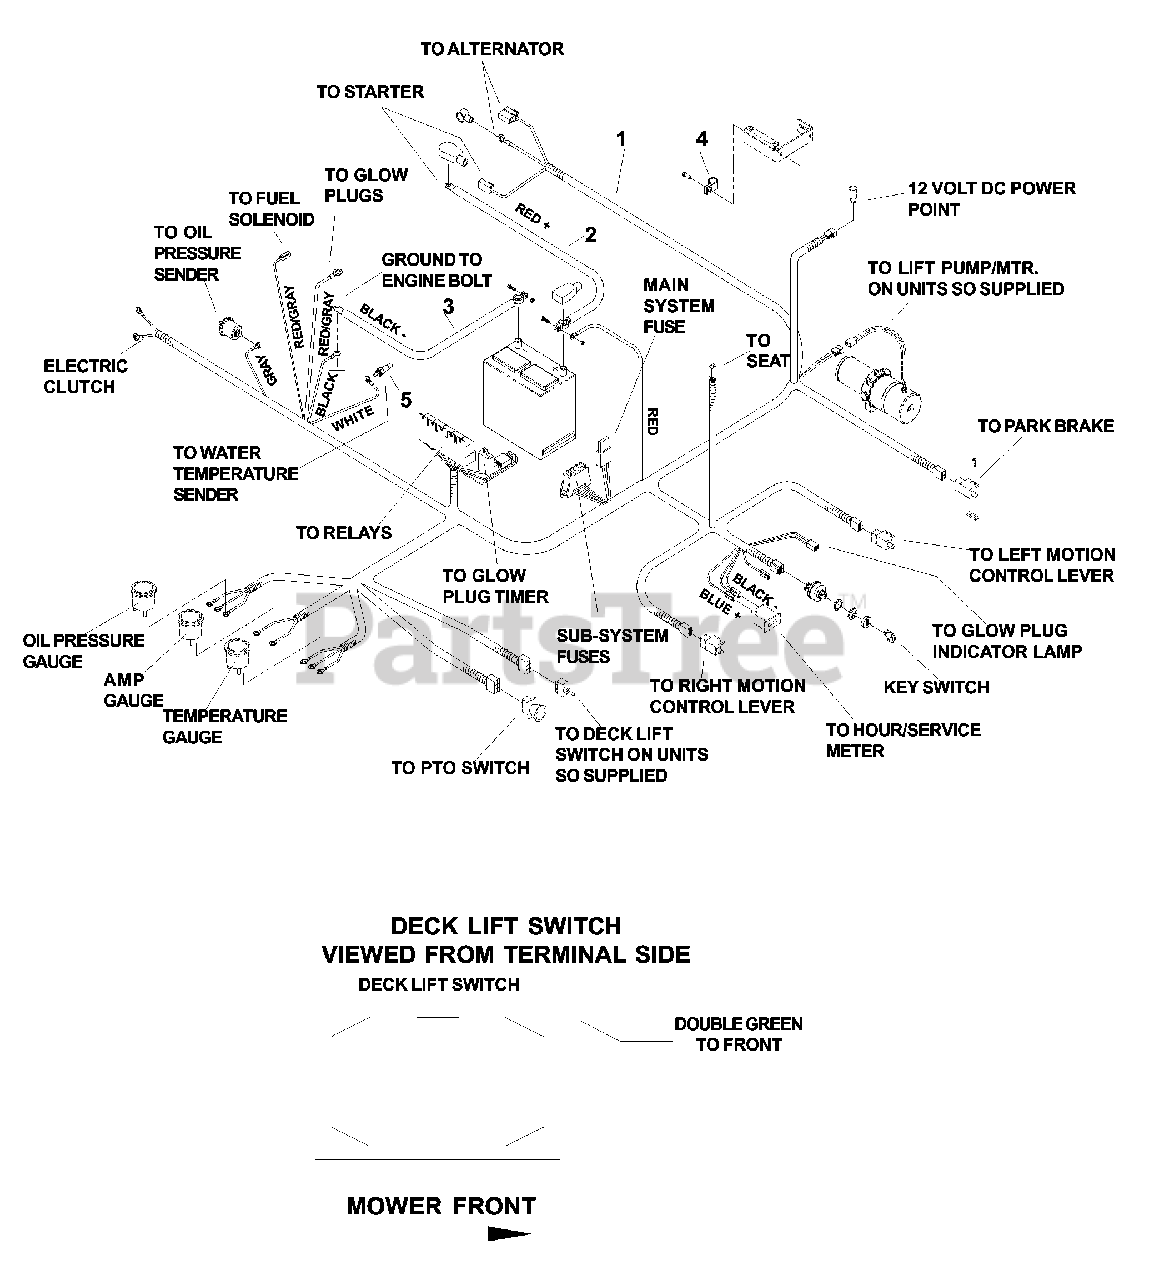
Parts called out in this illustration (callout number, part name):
1	Harness, engine, diesel
2	Cable, postive
3	Cable, negative
5	Sender, temperature
